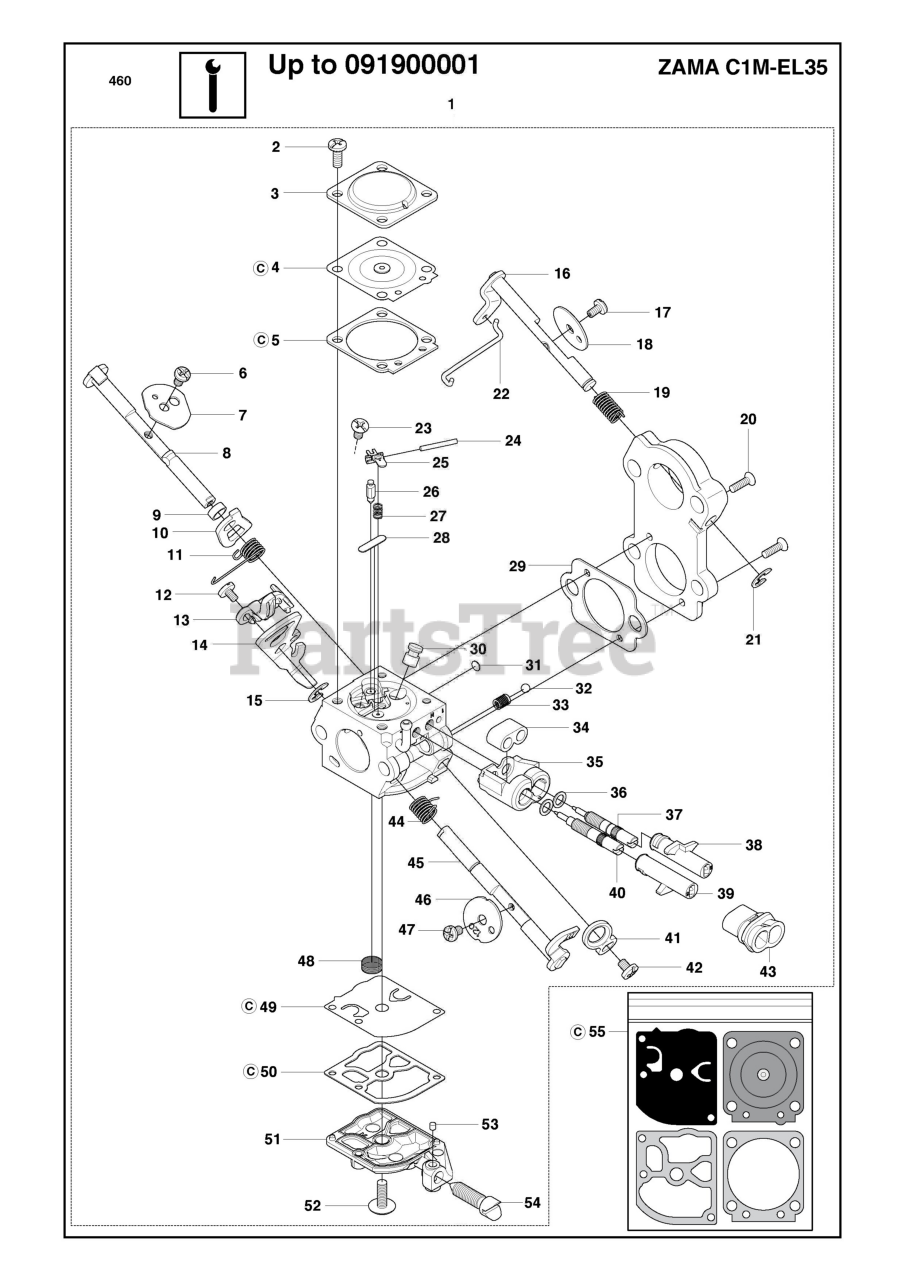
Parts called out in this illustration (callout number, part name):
1	%CARBURETOR
8	Shaft Assembly
16	Shaft Assembly
24	PIN FULCRUM
26	INLET NEEDLE
30	Nozzle Assembly
37	Screw
40	LOW SPEED NEEDLE
43	SLEEVE
45	Shaft Assembly
49	PUMP DIAPHRAGM
55	GASKET PACK
